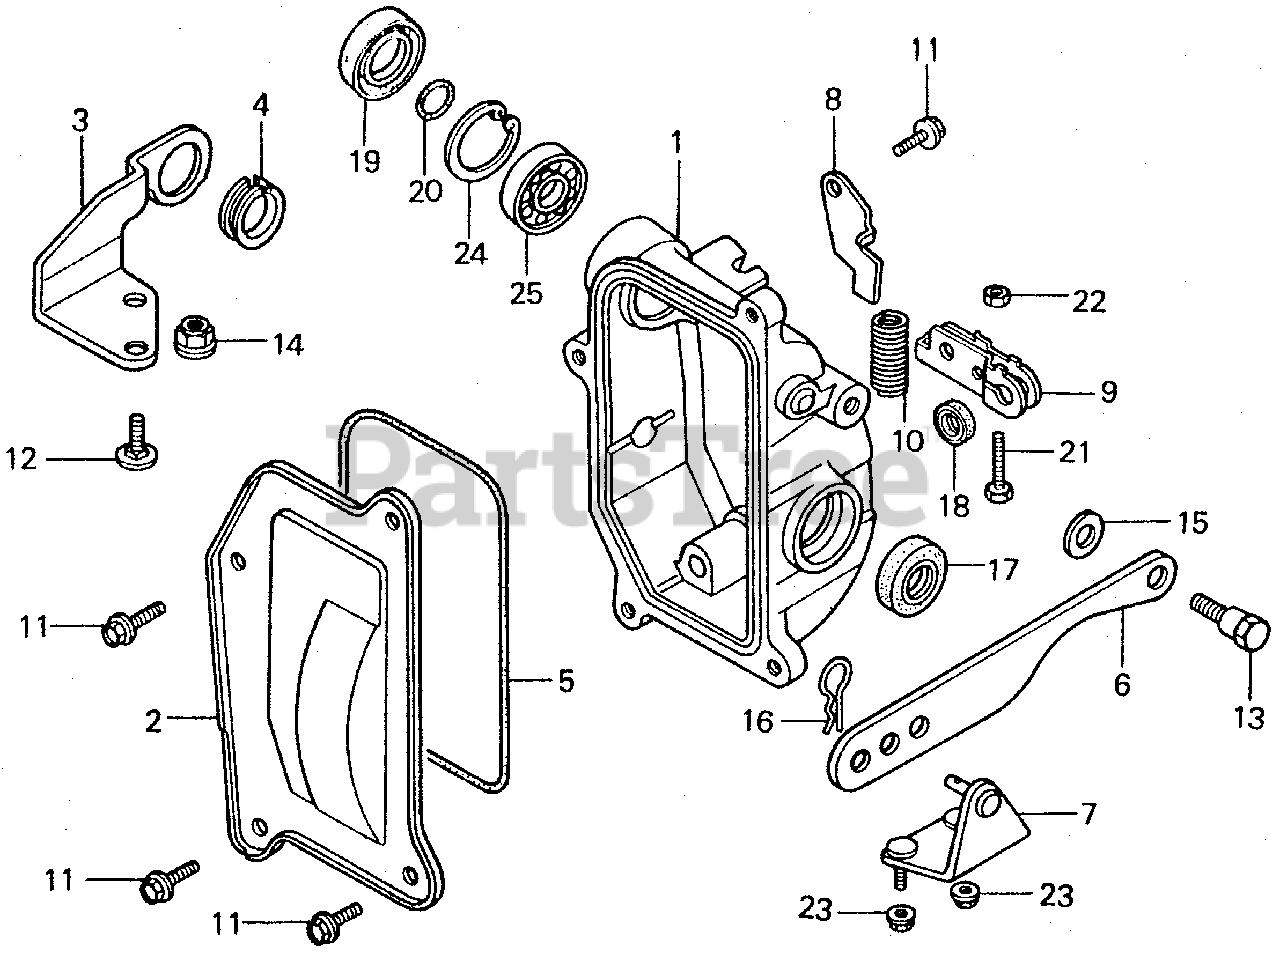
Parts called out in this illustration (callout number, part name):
1	CASE, TRANSMISSION (NOT AVAILABLE)
2	COVER, CASE
3	STAY A, CASE MOUNTING (NOT AVAILABLE)
4	BUSH, CASE MOUNTING (NOT AVAILABLE)
5	O-RING, CASE (NOT AVAILABLE)
6	ARM, CHANGE
7	STAY, CHANGE ARM
8	HOLDER, WIRE
9	ARM, CLUTCH (NOT AVAILABLE)
10	SPRING, CLUTCH RETURN
11	BOLT, FLANGE (6X12) (CT200)
12	BOLT, SPECIAL (9X15)
13	BOLT, MUFFLER SETTING (NOT AVAILABLE)
14	NUT, FLANGE (8MM)
15	WASHER, THRUST (8MM)
16	PIN, SNAP (7MM)
17	OIL SEAL (12X22X5)
18	OIL SEAL (8X14X5)
19	OIL SEAL (18X38X6) (NOT AVAILABLE)
20	O-RING (11.7X1.2) (NOT AVAILABLE)
21	BOLT, HEX. (6X20)
22	NUT, HEX. (6MM)
23	NUT, FLANGE (6MM)
24	CIRCLIP (INNER) (28MM)
25	BEARING, RADIAL BALL (6001)
